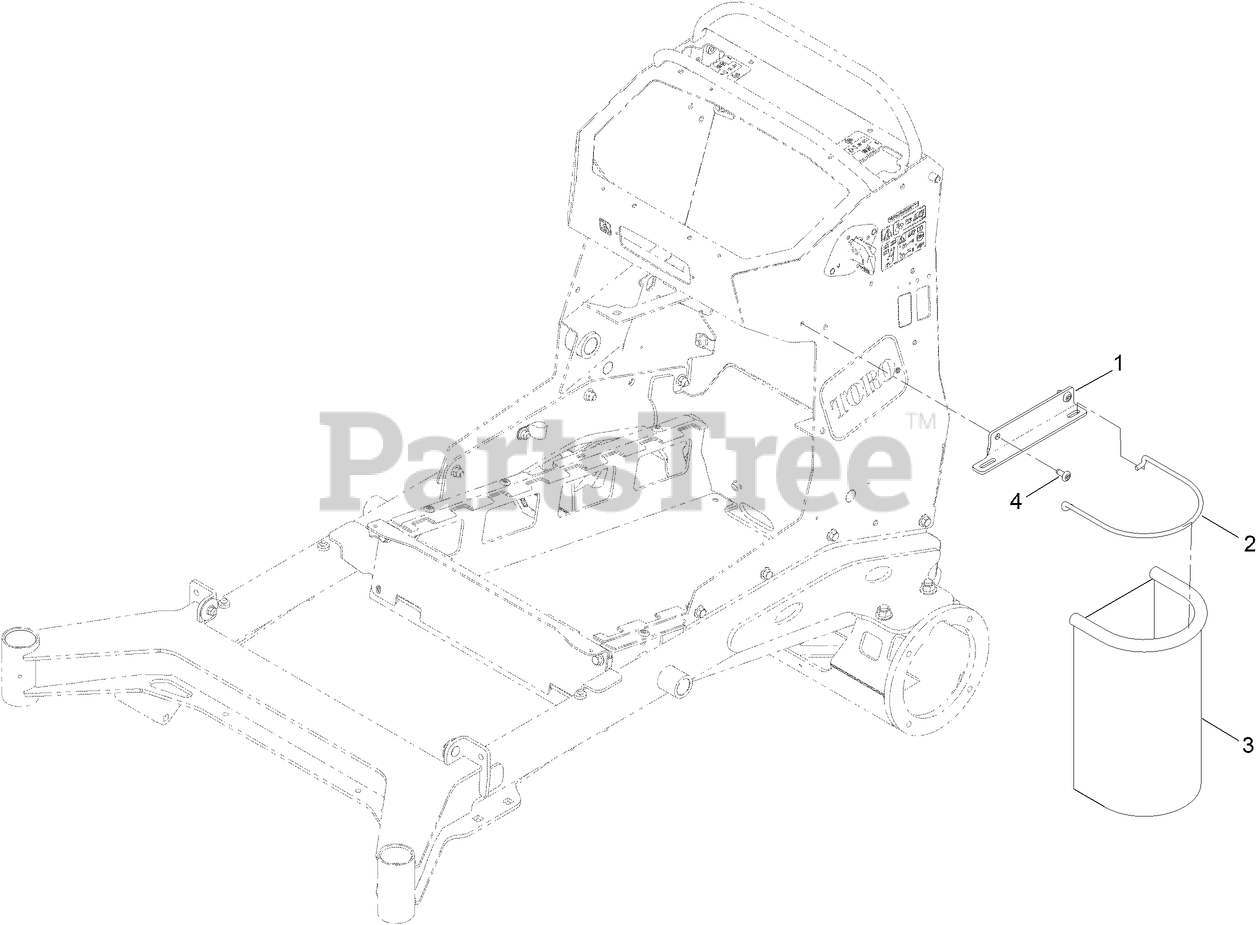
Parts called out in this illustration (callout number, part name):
1	BRACKET-BAG
2	ROD-BAG, TRASH
3	BAG-TRASH
